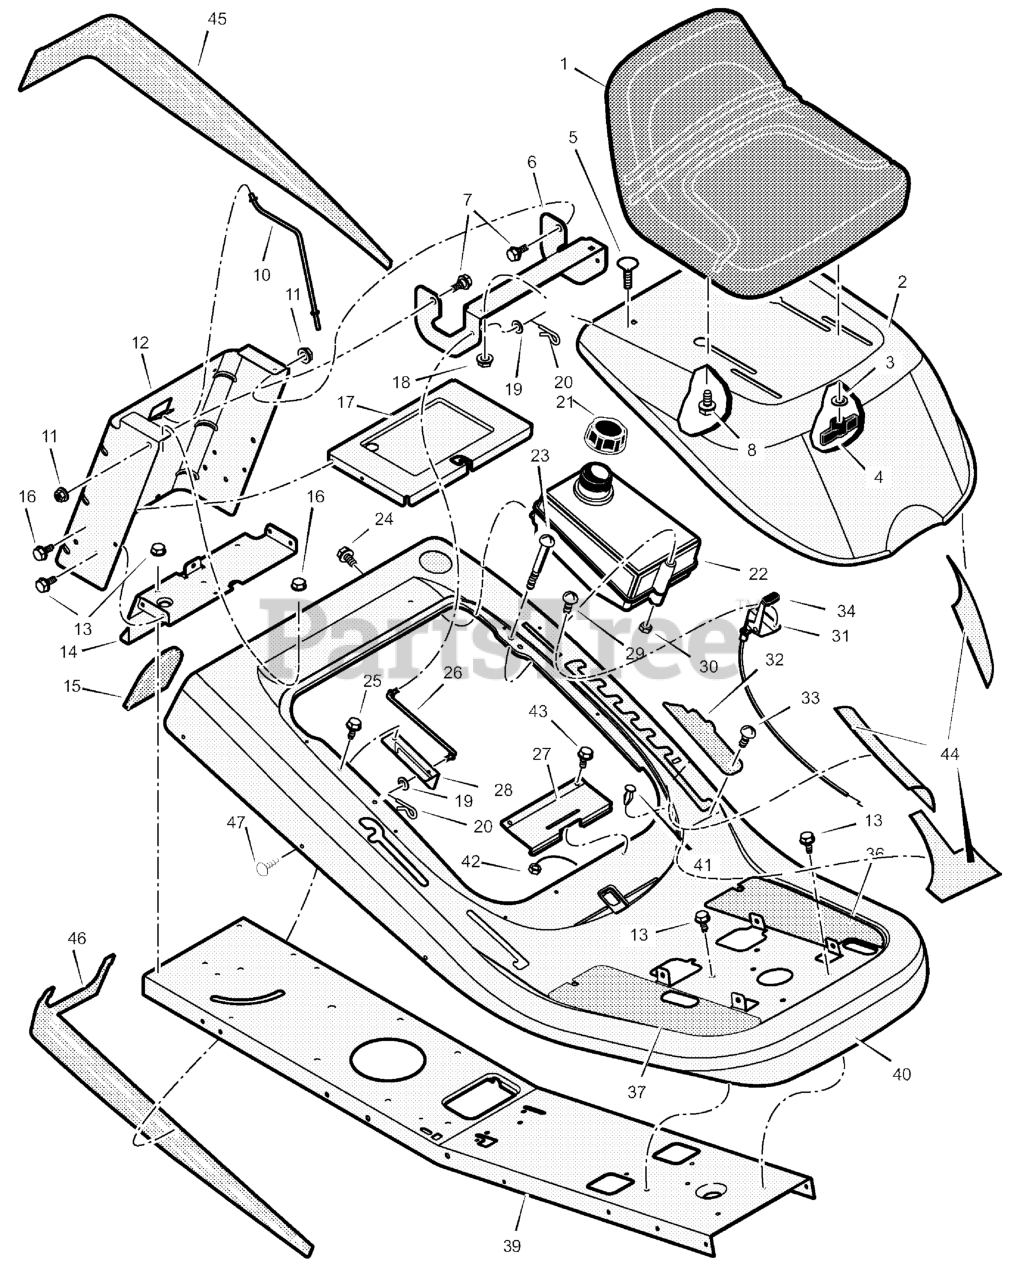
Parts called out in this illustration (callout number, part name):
1	Seat
3	Washer
4	Bolt, Wing
5	Bolt, Carriage
6	Bracket, Hinge
7	Bolt, Shoulder
8	Bolt, Shoulder
10	Rod, Battery
11	Nut, Flange
12	Plate, Rear
14	Plate, Hitch
15	Cover (Black)
17	TRAY, Battery
18	Nut, Flange
19	Washer
20	Pin, Cotter
21	Cap, Fuel Tank
22	Tank, Fuel
23	Screw
26	Rod, Hood Prop
27	Spring, Seat Deck
28	Bracket, Prop Rod
30	Nut, NY-Lock
31	Control, Throttle
32	Cover, Detent (Black)
33	Bolt, Shoulder
36	Footmat, Left
37	Footmat, Right
41	Bumper
42	Nut
43	Screw
44	Kit, Foil Heat Shield
45	Trim, Left (Black)
46	Trim, Right (Black)
47	Fastener, Panel
